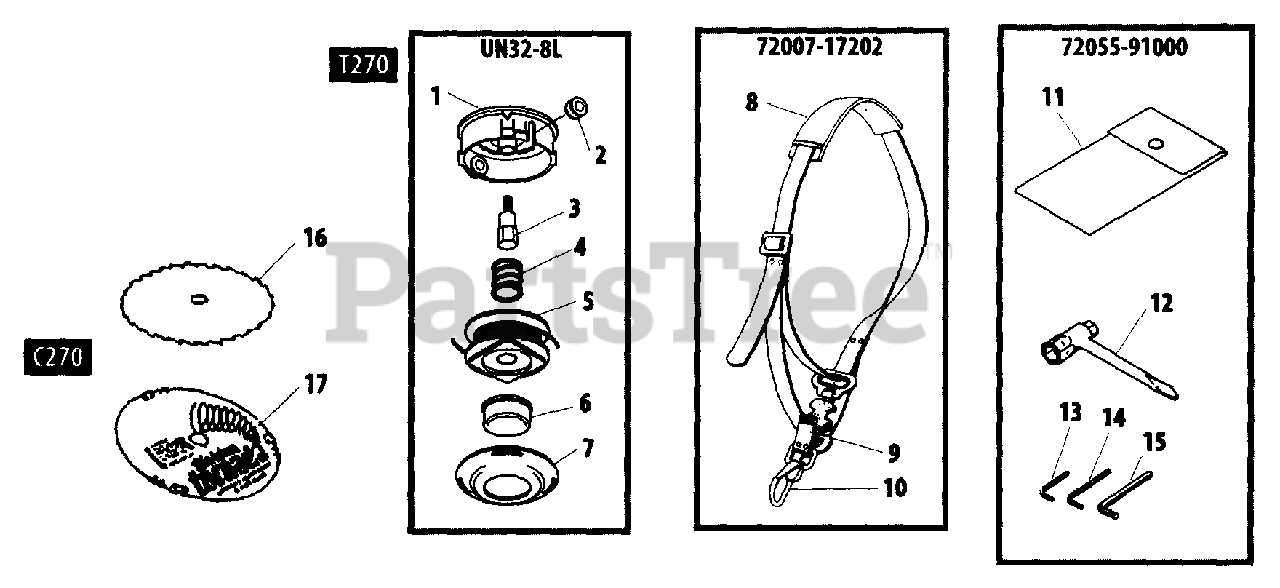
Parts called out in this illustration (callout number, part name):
3	SHAFT BOLT
8	PAD, SHOULDER
10	HOOK, SNAP
11	BAG, TOOL
12	T-WRENCH 13×19 MM
13	WRENCH, ALLEN 3 MM
14	WRENCH, ALLEN 4 MM
15	WRENCH, ALLEN 5 MM
16	BLADE, 25 MM ID - 30 TOOTH -- 8"
17	BLADE - 6 TOOTH -- 9" TORNADO
